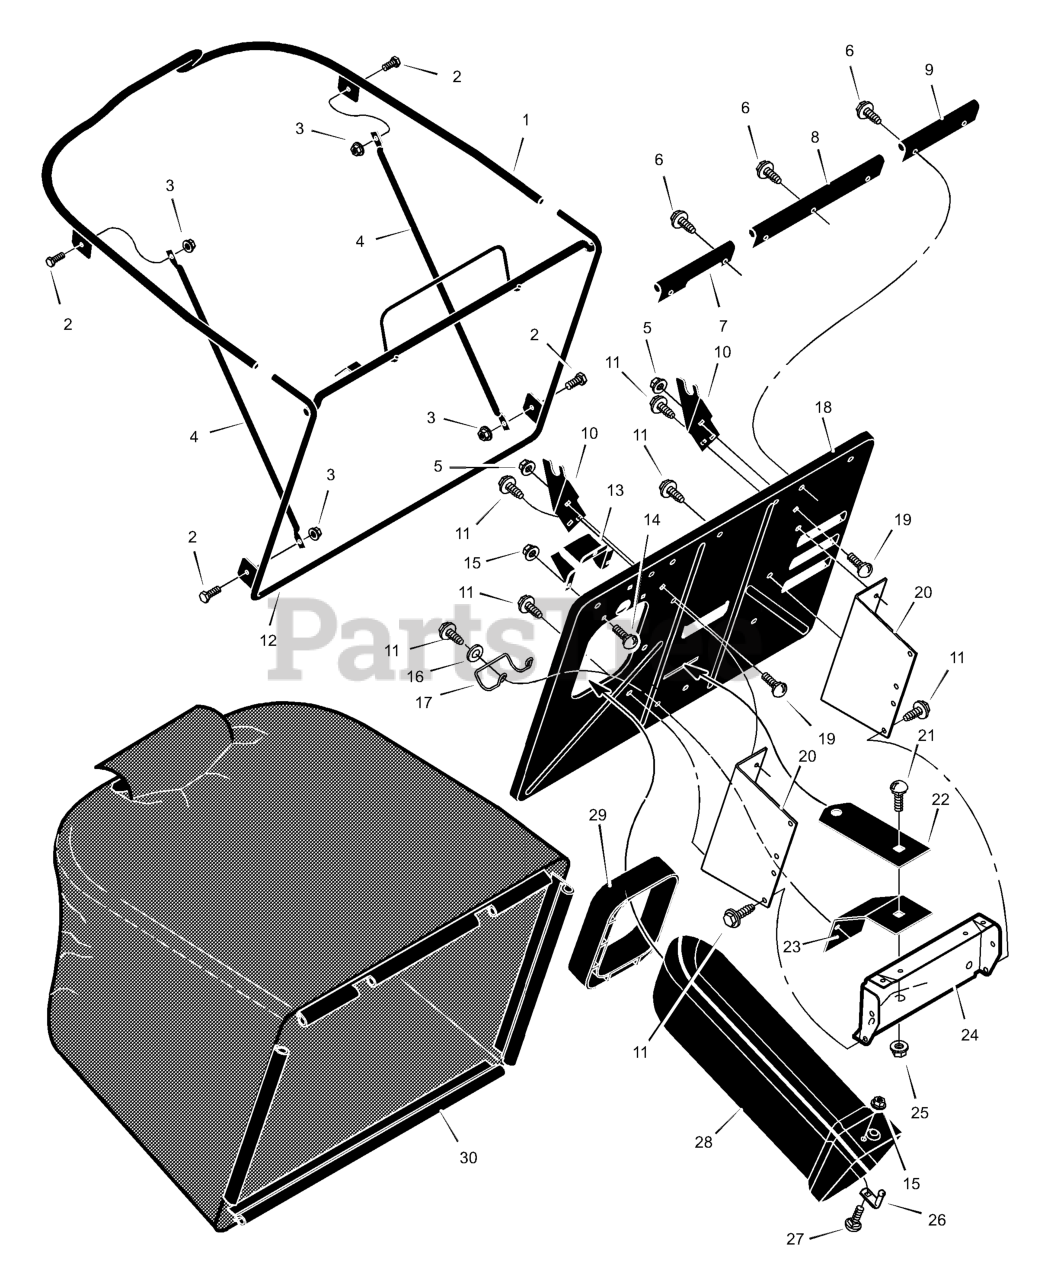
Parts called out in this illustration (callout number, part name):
1	Tube, Top
3	Nut
4	Strut, Bag
5	Nut, Flange
6	Fastener, Panel
7	Seal, Bag (Right End)
8	Seal, Bag (Center)
9	Seal, Bag (Left End)
10	Hinge
12	Assembly, Bag Frame
13	Bracket, Switch
14	Bolt, Carriage
15	Nut, Flange
16	Washer
17	Latch, Spring
18	Pan, Rear
19	Bolt, Carriage
20	Bracket, Bagger Mounting
22	Plate, Hitch Extension
23	Bracket, Lower Mounting
24	Plate, Hitch
26	Pin, Latch
27	Bolt, Carriage
28	Tube, Connecting
29	Grommet, Extension Tube
30	Bag, Grass
